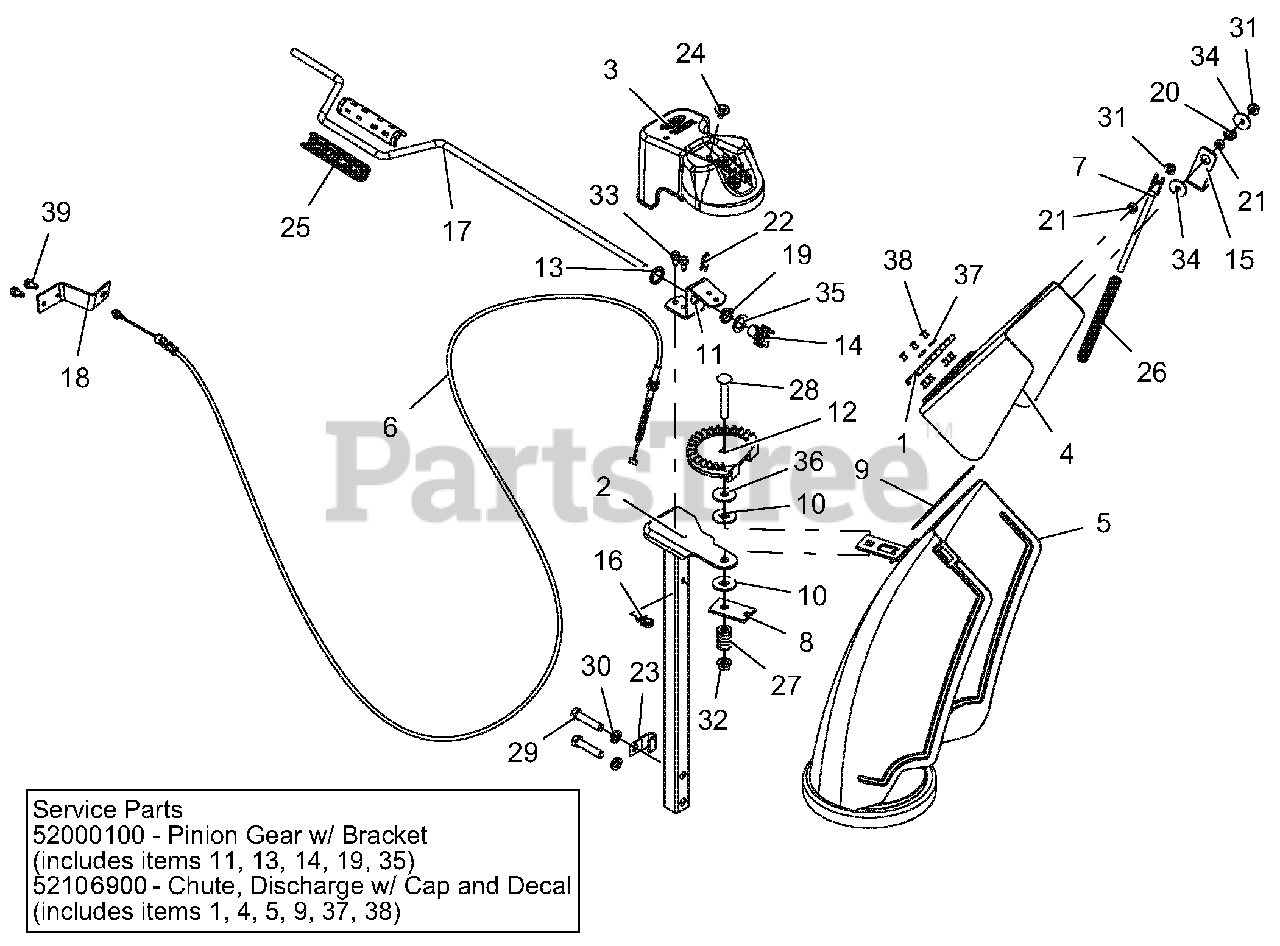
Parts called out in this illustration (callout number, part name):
2	PEDESTAL, CHUTE - CRANK
3	GEAR COVER ASSY LG SHEAR BOLT
4	CAP,LARGE,REMOTE
5	CHUTE,DISCHARGE,RMT,ID
6	CABLE, DEFLECTOR - DELUXE
7	ROD, DEFLECTOR CAP
8	PLATE, FRICTION
9	CAP SEAL 5.50
10	FRICTION WASHER
11	BRACKET, PINION GEAR
12	CHUTE GEAR
13	PUSHNUT .625
14	PINION GEAR - CHUTE
15	BRACKET, CABLE ANCHOR
16	CLIP, CABLE GUIDE
17	ROD, CHUTE CRANK
18	ANCHOR, DEFLECTOR CABLE
19	BUSHING, POLYLINER-.63 SNAPIN
20	BUSHING, POLYLINER-.50 SNAPIN
21	BSHG-SLV .265X.500X.219
22	PIN, SPRING CLIP
23	J-CLAMP
24	SCR-TAP .25-20X.50 LGHWH TR YZ
25	KNOB, CRANK-SNAP
26	SG-COMP .08X.40X6.50 14#/IN
27	SG-COMP .187X.56X1.62
28	@BLT-RDHDSQNK .38-16X2.50 G5YZ
29	@BLT-HEX .38-16X1.75 GR5 YWZC
30	@WSHR-LK .38X.094 REG YWZC
31	@NUT-LK-CTR-FLG .25-20 YWZC
32	@NUT-LK-TOP-FLG .38-16 YWZC
33	SCR-TAP .25-20X.50 HWH TR YWZ
34	WSHR-FL-STL .281X1.000X.063
35	WSHR-THRST .625 X 1.0 X .03
36	@WSHR-FL-STL .406X1.25X.10 ZC
37	WSHR-FL-STL .196X.500X.06 YZ
38	RVT-POP .187 YZ
39	SCR-TAP .25-20X.50 HWH TR YWZ
